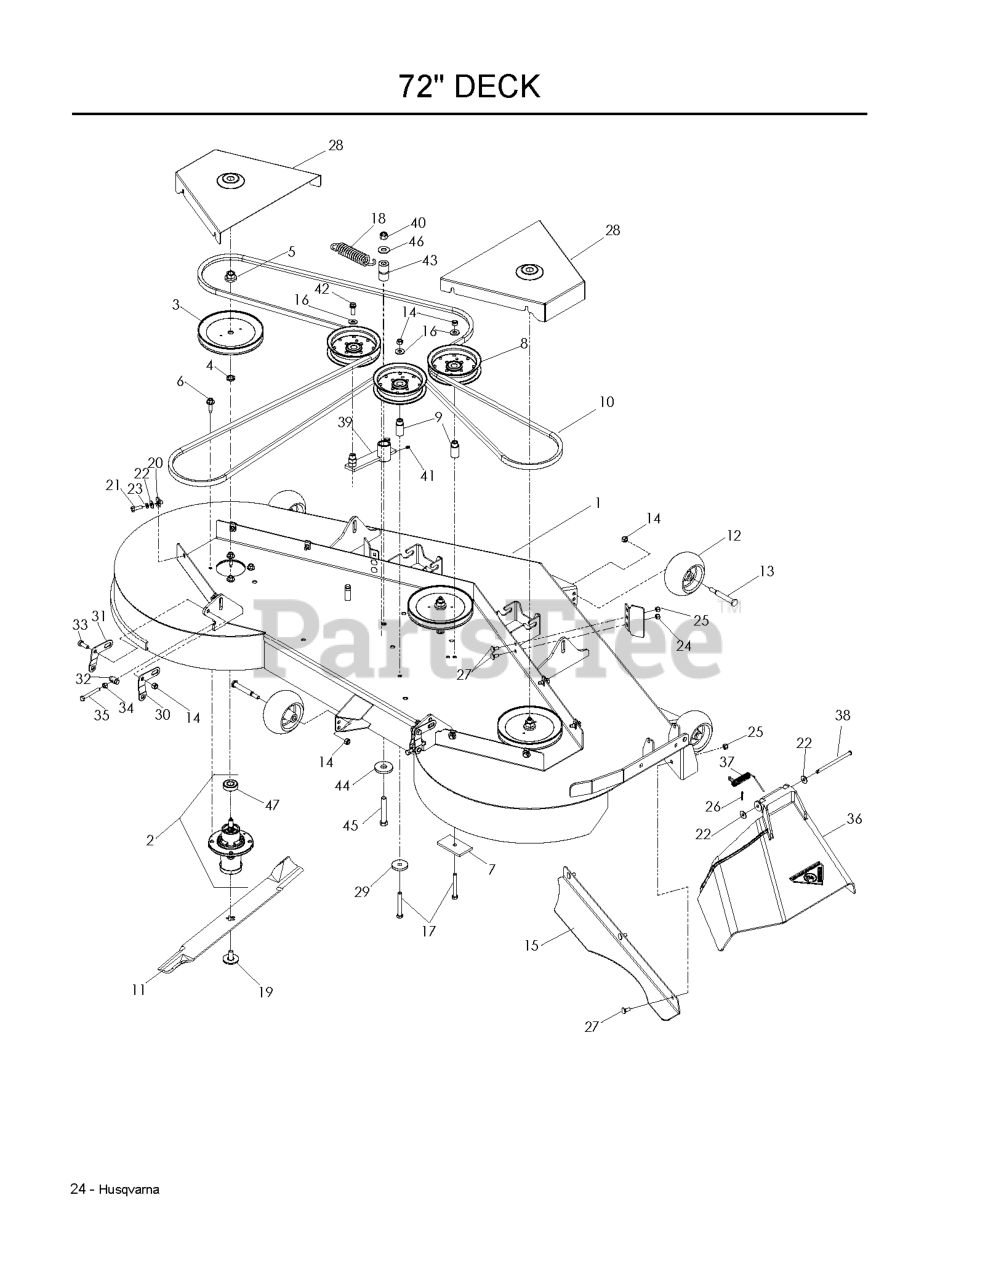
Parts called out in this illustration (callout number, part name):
1	PILLOW BLOCK
2	CROSS LINK
3	IDLER SPACER
4	PEDAL, FOOT, HEX
5	SHAFT, FRONT-LIFT
6	REINFORCEMENT BAR
7	BELLCRANK, RR, LIFT
8	STRUT LINKAGE
9	LIFT CHAIN - 3 LINK
10	HCS 7/16C X 1 1/2
11	HCS 7/16 - 14 X 1 3/4
12	NUT 7/16C WHIZ
13	NUT 7/16-14 HEX WHIZ LK
14	BELLCRANK, RR, RT
15	LATCH, TRANSPORT
16	HEIGHT, ADJUST, DECK
17	PIVOT, LATCH, TRANSPORT
18	SPACER, .3
19	PIN, 1/2 X 1 1/2, DETENT RING
21	WASHER 1/2" FLAT
22	PIN, COTTER 1 3/4
23	HHCS 1/2-13 X 1
24	WASHER, 7/16 DISC SPRING
25	HCS 5/16C X 2-3/4
26	5/16-18 NYLOC FLANGE NUT
27	HCS 1/2-13 X 1 3/4 GR 8
28	WASH USS FLAT 1/2
29	NUT 1/2-13 HEX NYLOC ZD
30	NUT 3/8-16 NYLOC
31	HCS 3/8C X 1 1/4 GR5
32	NUT HEX 3/8-16 NYLON, THIN
33	HCS 3/8C X 3
35	MOUNT, SPRING
36	TAB, SPRING
39	NUT 5/16 NYLOC
40	BOLT 5/16-18 X 3/4
41	HHFS 3/8-16 X 2 3/4
42	MOUNT, STRUT
43	SPRING, TORSION
44	GRIP, TRANSPORT-RELEASE
45	SUPPORT, LIFT ROD
